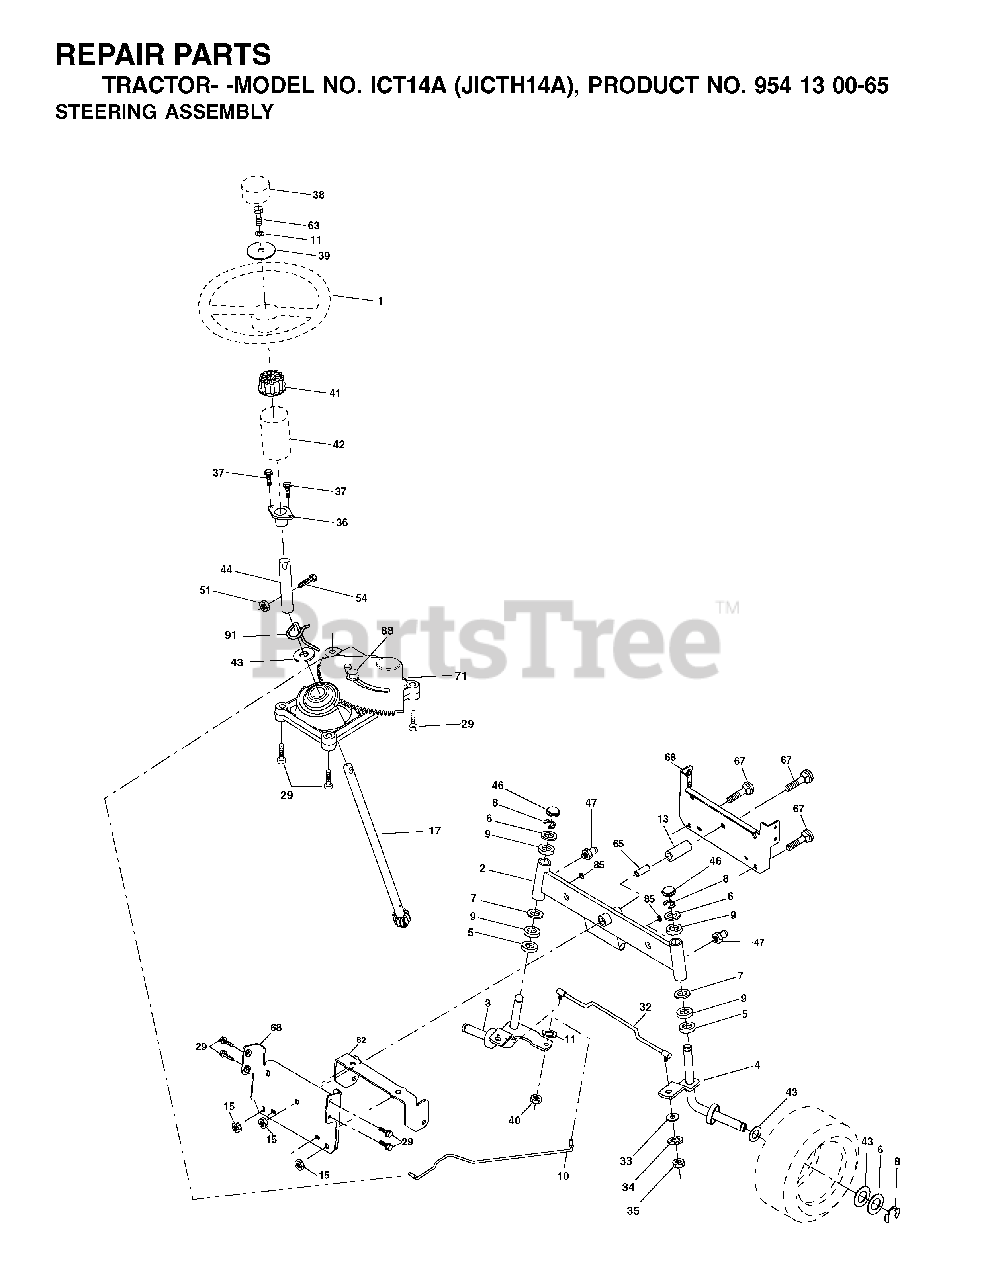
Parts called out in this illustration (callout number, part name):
2	AXLE ASM
3	SPINDLE.ASM.LH.15"TIRES
4	SPINDLE.ASM.RH.15"TIRES
8	RING CLIP
10	DRAGLINK.15".TIRES.2001
11	WASHER, LOCK 3/8
13	TUBE, PIVOT AXLE
15	NUT
17	SHAFT ASM
29	SCREW 3/8-16X3/4
32	ROD.ASM.TIE.BALL.JOINT.NOVAN
33	WASHER M
34	LOCKWASHER
35	NUT, CROWNLOCK
36	BUSHING, STEERING
39	WASHER 13/32 X 2-3/8 X 12 GA
40	GRIPCO NUT
41	STEERING WHEEL ADAPTOR
42	BOOT.STEERING.SHAFT.BLACK
44	EXT SHAFT STEERING
46	CAP.SPINDLE
51	NUT.71038.31-18.HEX.NYLOCK
54	BOLT.5/16-18X1-1/4 FULL.THREAD
65	SPACER BRACE AXLE
67	BOLT
68	BRACE.AXLE.15"TIRES
71	STEERING ASM
82	BRACKET
87	WASHER, FLAT .781 X 1 1/2"
88	BOLT, SHOULDER 7/16-20
91	CLIP.STEERING
